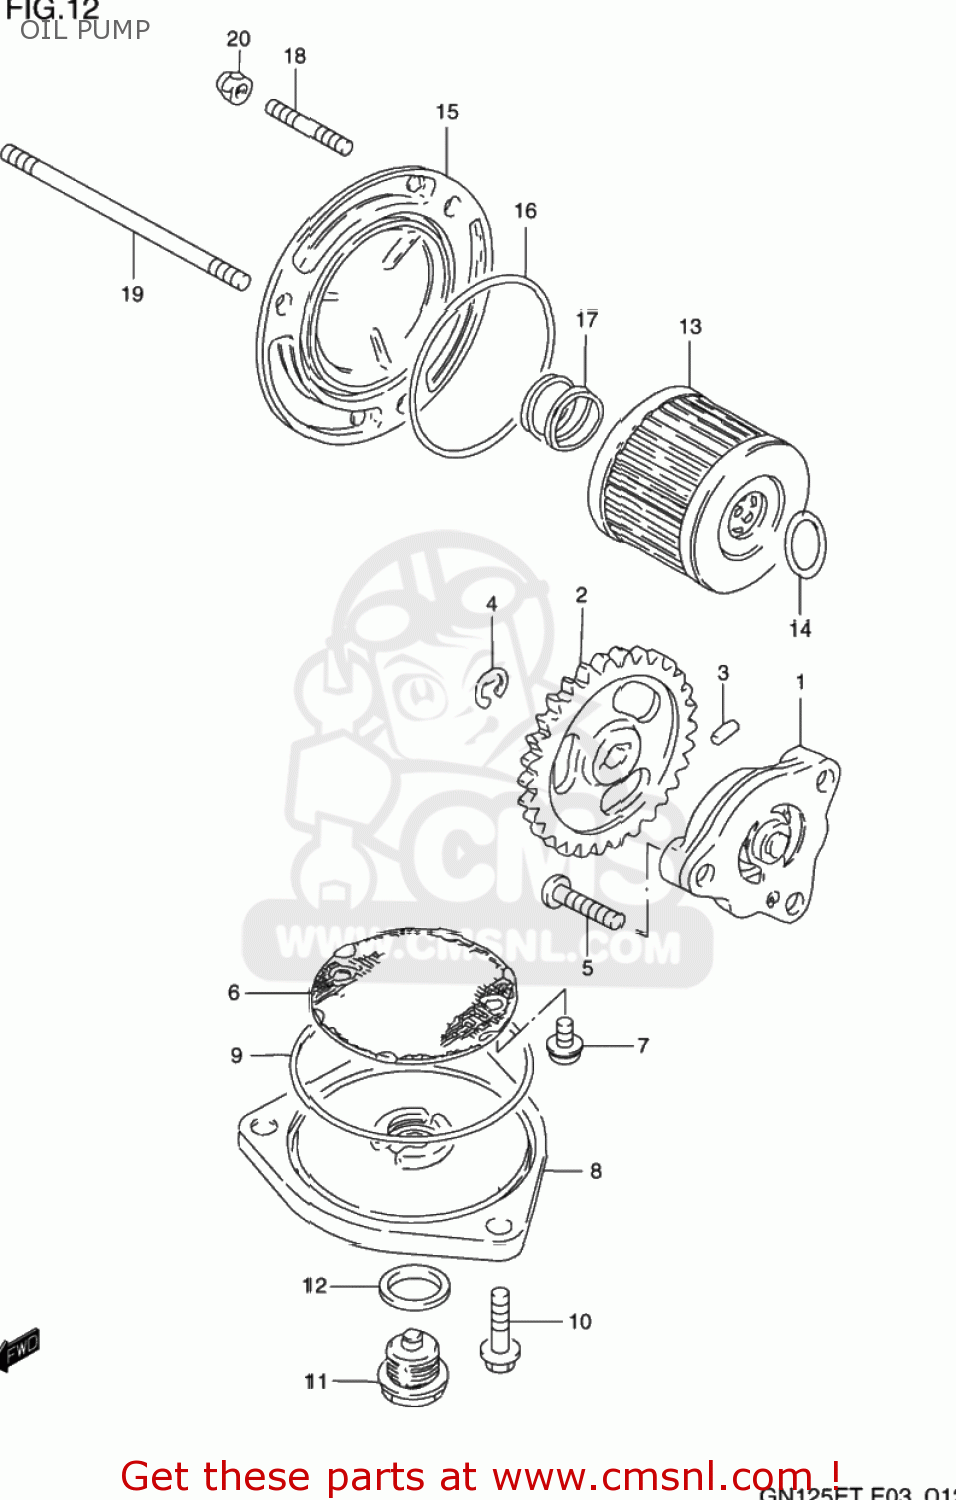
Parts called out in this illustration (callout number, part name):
1	PUMP ASSY,ENGINE OIL
2	GEAR,ENG OIL PUMP DRIVEN(NT:30
3	PIN(2.5X11.8)
4	E.RING
5	SCREW
6	STRAINER,ENGINE OIL
7	SCREW
8	CAP,OIL STRAINER
9	O RING(D:2.4,ID:60.5)
10	BOLT
11	PLUG
12	GASKET(14X19.2X2) (NAS)
13	FILTER ASSY,ENGINE OIL
14	O RING(D:1.9,ID:13)
15	CAP,OIL FILTER
16	O RING(D:2.4,ID:52.6)
17	SPRING
18	STUD 6X12
19	STUD BOLT, 6X8
20	NUT
